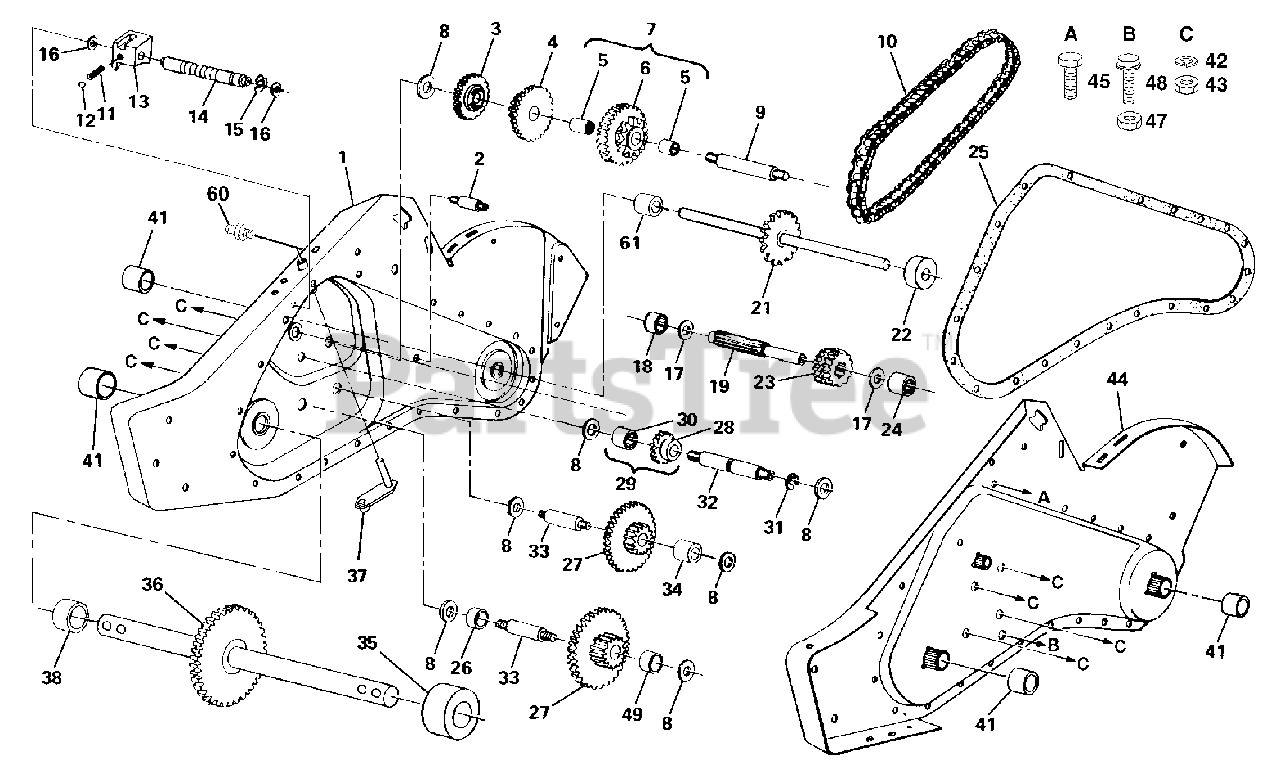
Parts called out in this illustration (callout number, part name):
1	Gearcase, R.H. w/Bearing
2	Spacer Gearcase
3	Gear Reverse
4	Gear, Cluster, Red 1st & 2nd
5	Bearing, Needle
6	Sprocket and Tine Assembly
7	Sprocket Assembly w/Bearing
9	Shaft, Reduction (1st)
10	Chain, Roller
11	Spring, Shift, Fork
12	Ball, Steel
13	Fork, Shift
14	Shaft, Reduction
15	Ring, Klip
16	Washer, Seal
17	Washer, Thrust 5/8 ID
18	Bearing, Needle
19	Shaft Input
21	Tine Shaft Assembly
22	Spacer 1,008 x 1-3/4 x 0,645
23	Pinion, Input
24	Bearing, Needle
25	Gasket, Gearcase
26	Spacer 0,765 I.D. x 1,12 x 5/8
27	Gear Cluster
28	Gear, Reverse Idler
29	Gear, Assembly, Reverse Idler
30	Bearing, Needle
31	Ring, Klip
32	Shaft, Reverse Idler
33	Shaft, Reduction (2nd)
34	Spacer 0,765 I.D. x 1-1/8 x 1-3/8
36	Shaft Assembly
37	Bracket, Asm.
41	Seal, Asm OIl
42	Push Nut 7/16
43	Nut, Hex 7/16-20
44	Gearcase, L.H. w/Bearing
45	Bolt 5/16-18 He Whs Hd Lckserr
47	Nut, Hex 5/16-18
48	Screw 5/16-18 x 4
49	Spacer 0.765 ID x 1.12 x 3/4
60	Fitting, Grease
61	Spacer 1.015 x 1.50 x .765
